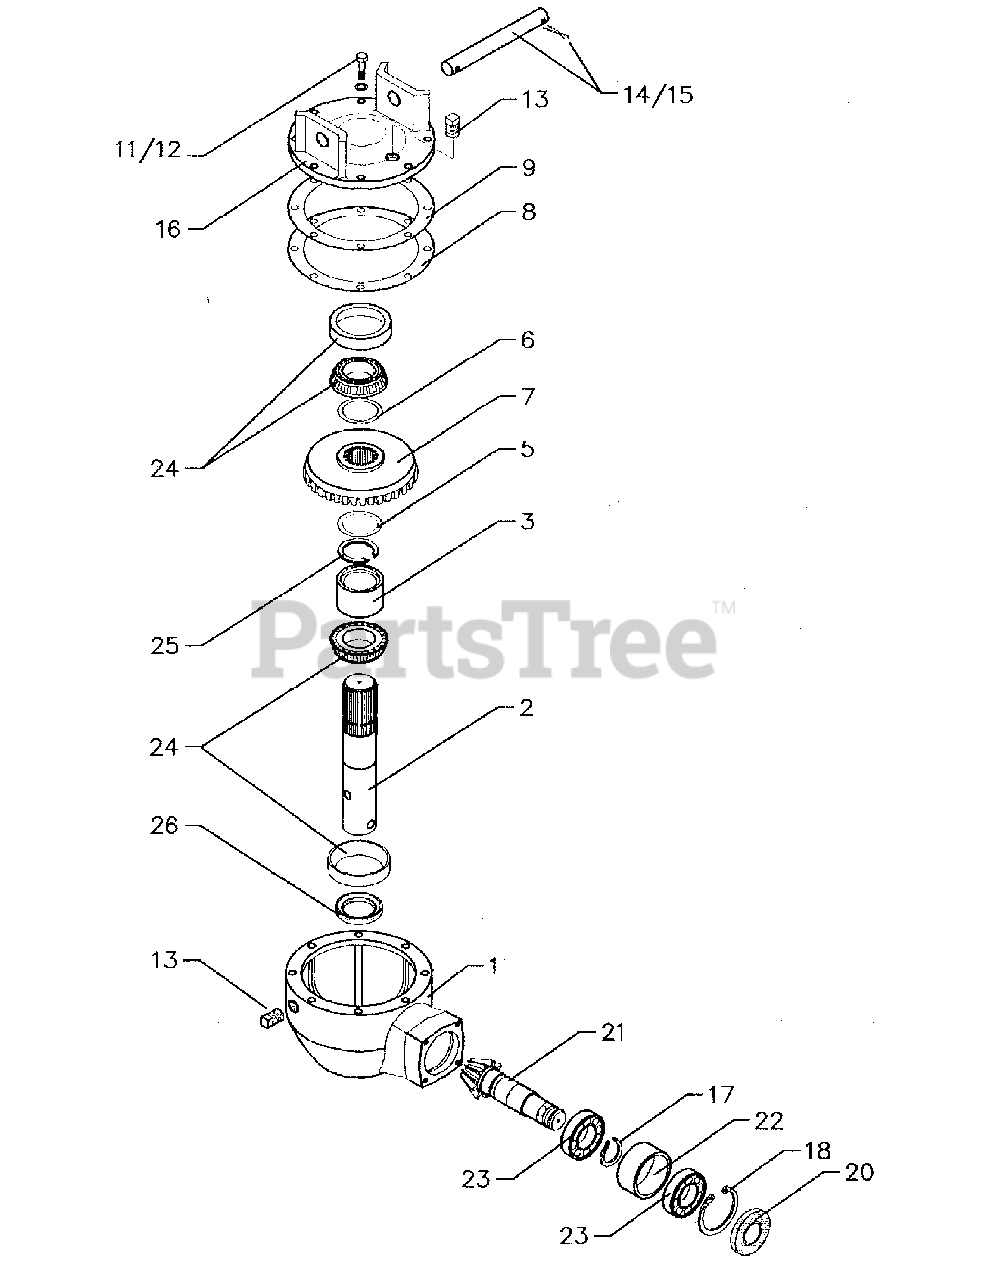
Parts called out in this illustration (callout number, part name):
1	HOUSING
2	OUTPUT SHAFT
3	OUTPUT BEARING SPACER
5	GEAR ADJUSTING SHIM .03
6	GEAR ADJUSTING SHIM .50
7	OUTPUT GEAR 33 TOOTH
8	OUTPUT CAP GASKET .10
9	OUTPUT CAP GASKET .25
11	LOCKWASHER M10
12	CAP SCREW M10 X 30
13	PIPE PLUG 1/2"
14	HANGER SHAFT
15	COTTER PIN
16	HANGER CAP
17	RETAINING RING
18	RETAINING RING
20	INPUT SEAL
21	PINION GEAR & SHAFT 11 TOOTH
22	BEARING SPACER
23	BEARING 6207
24	BEARING 7210 & RACE
25	RETAINING RING
26	OUTPUT SEAL 50 X 70 X 12
